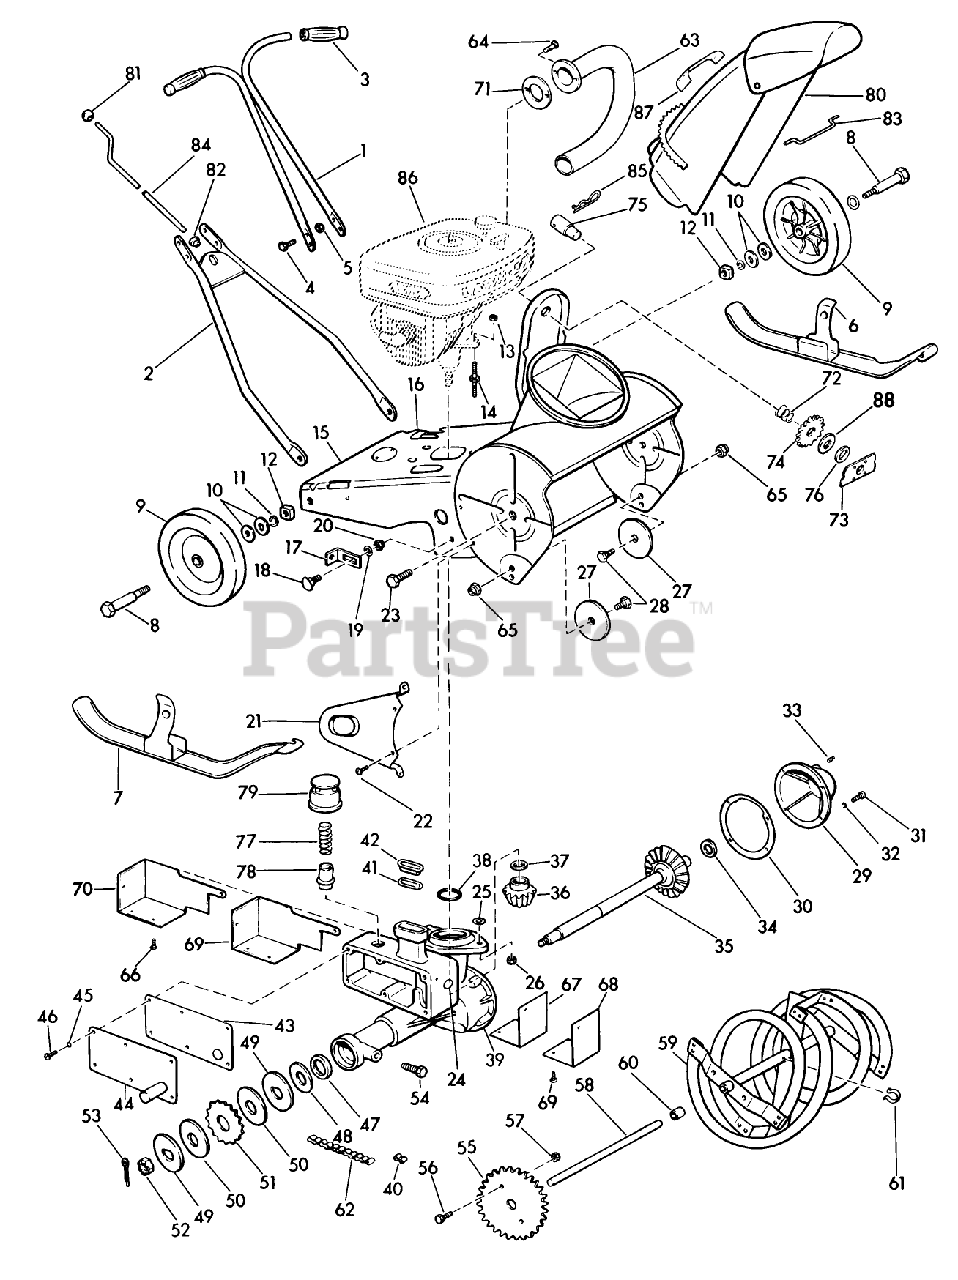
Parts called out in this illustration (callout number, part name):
5	STOP NUT
10	WASHER WROUGHT
11	WASHER, LOCK
15	Base, Housing and Bracket Assy.
20	Nut-Huglok
24	Plug-Core
25	Washer-G-case to Base Stud
28	Stud-Front Wheel
29	Cover-Gearcase
31	Screw-Gearcase Cover
34	Thrust Washer-Driveshaft Gear
35	Driveshaft and Gear Assembly
37	Thrust Washer-Pinion Gear
38	O Ring-G-case to Crankcase
49	Washer-Steel "D" Hole
53	Cotter Pin-Wheel
54	Screw-Stabilizer Bracket
57	Nut-Huglok
86	Lawn Boy Engine-D-470
87	Decal-Oil Instruction
